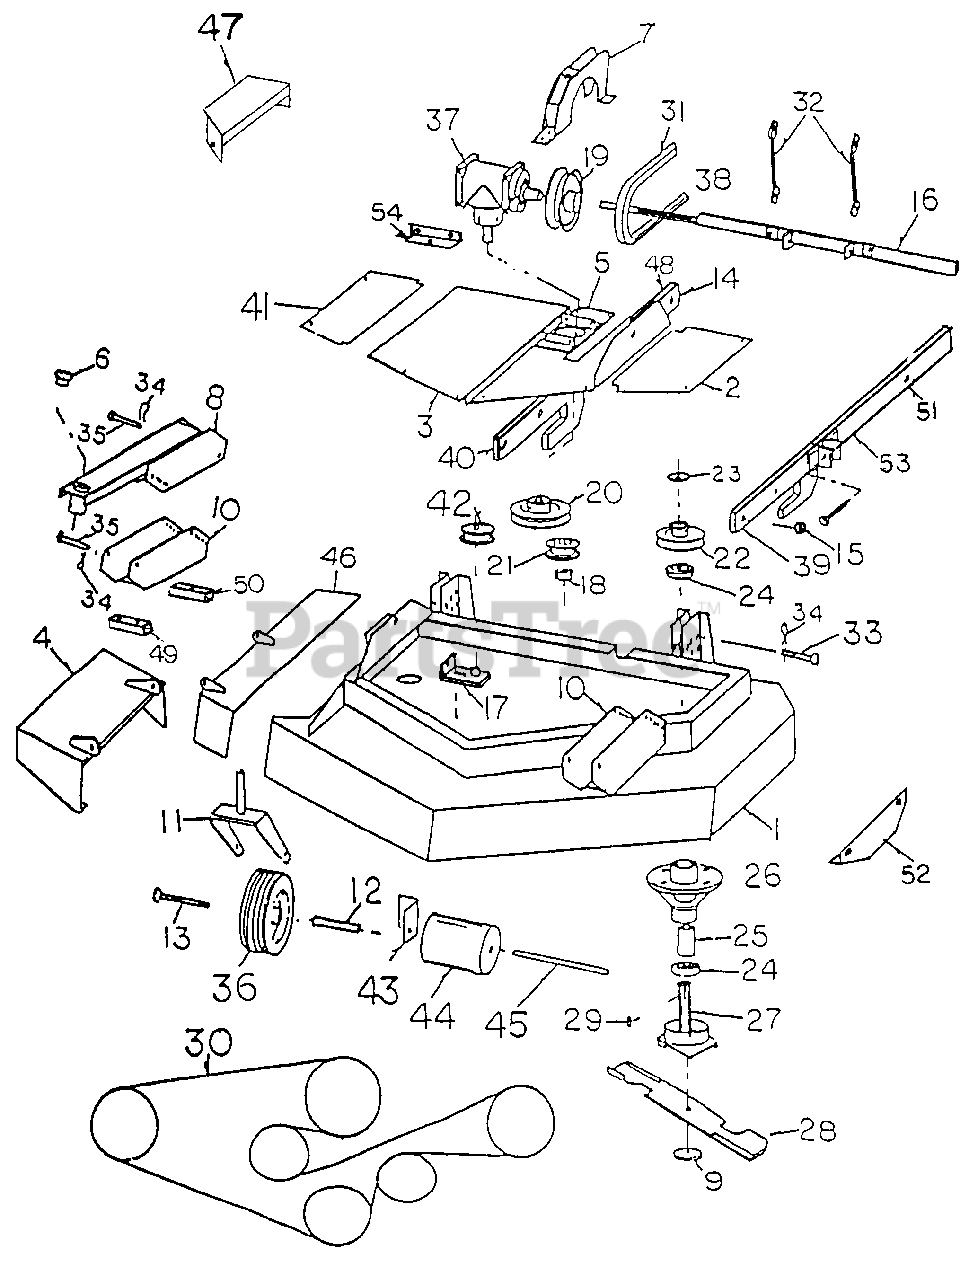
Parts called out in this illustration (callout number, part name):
5	GEAR BOX MOUNT
6	GAGE WHEEL BUSHING
8	GAGE WHEEL MOUNT
10	BRACKET, GAGE WHEEL MOUNT
11	FORK, GAGE WHEEL
12	AXLE, GAGE WHEEL
13	GACE WHEEL BOLT
14	DECK LIFT ARM BACK ADJUSTABLE
15	BUSHING, DECK LIFT ARM
17	BELT TIGHTENER
18	SPACER, IDLER
19	PULLEY, GEAR BOX
20	PULLEY, GEAR BOX
21	PULLEY, IDLER (SMALL)
22	PULLEY, SPINDLE
23	WASHER, SPINDLE
24	BEARING, SPINDLE
25	SPACER, SPINDLE
26	HOUSING, SPINDLE
27	SHAFT, SPINDLE
28	BLADE
29	KEY, SPINDLE
35	PINS, GAGE WHEEL
38	CROSS BAR PIN
39	DECK LIFT ARM FRONT ADJUSBABLE
40	DECK LIFT ARM FRONT ADJUSTABLE
41	COVER, RICHT HAND SIDE
42	PULLEY, IDLER (LARGE)
43	ROLIAR BRACKET
46	FOOT CUARD MOUNT
47	COVER, DECK BLOWER PULLEY
48	DECK LIFT ARM BACK ADJUSTABLE
49	GAGE WHEEL BRACKET SPACER 2 HOLE
50	CAGE WHEEL BRACKET SPACER 1 HOLE
51	DECK LIFT ARM BACK ADJUSTABLE
52	SHOE LEFT HAND SIDE
53	L.H. DECK LIFT BACK ADJUSTABLE
54	GEARBOX MOUNT ANGLE
